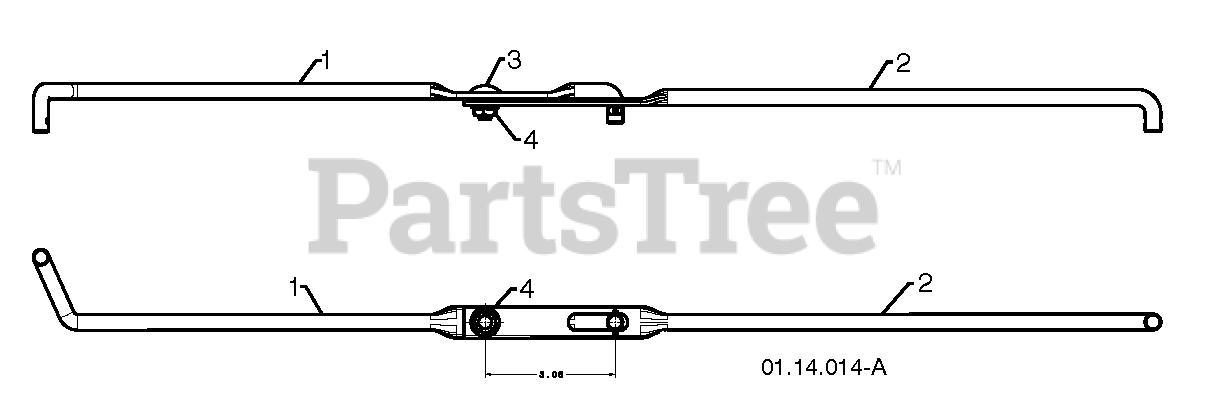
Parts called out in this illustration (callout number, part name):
1	ROD.SHIFTER.TOP.HYD.SNOW
2	ROD, LOWER, SPEED CONTROL
3	BOLT
4	NUT.FLANGE.5/16
